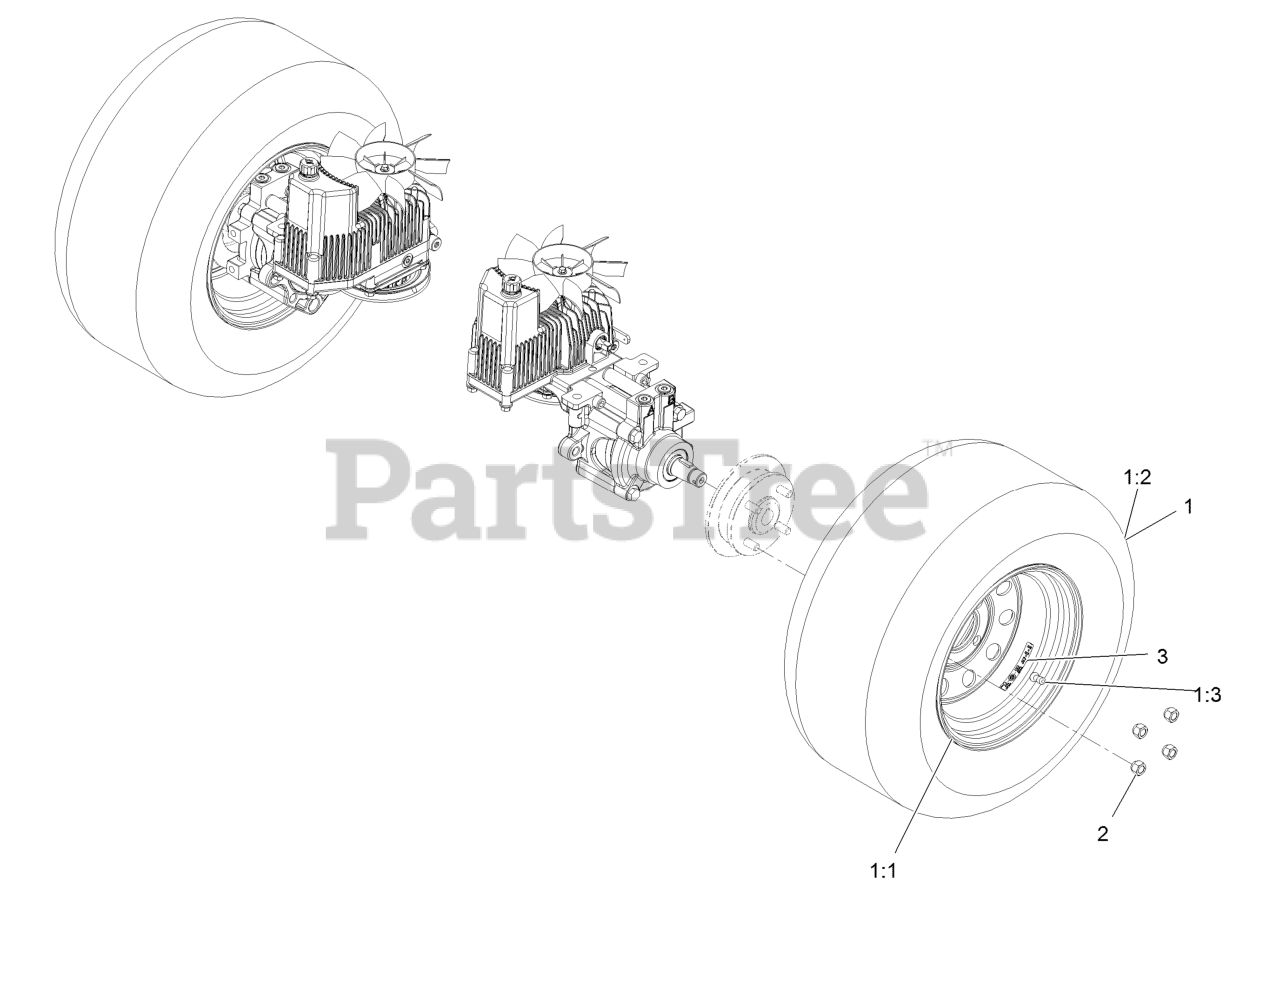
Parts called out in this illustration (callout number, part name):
1	ASM-Wheel And Tire
1:1	ASM-Rim 60
1:2	Tire-Drive
1:3	Stem-Valve
2	Nut-Lug 1/2-20
3	ASM-Rim 60Decal-Torque, Wheel Hub Lug
